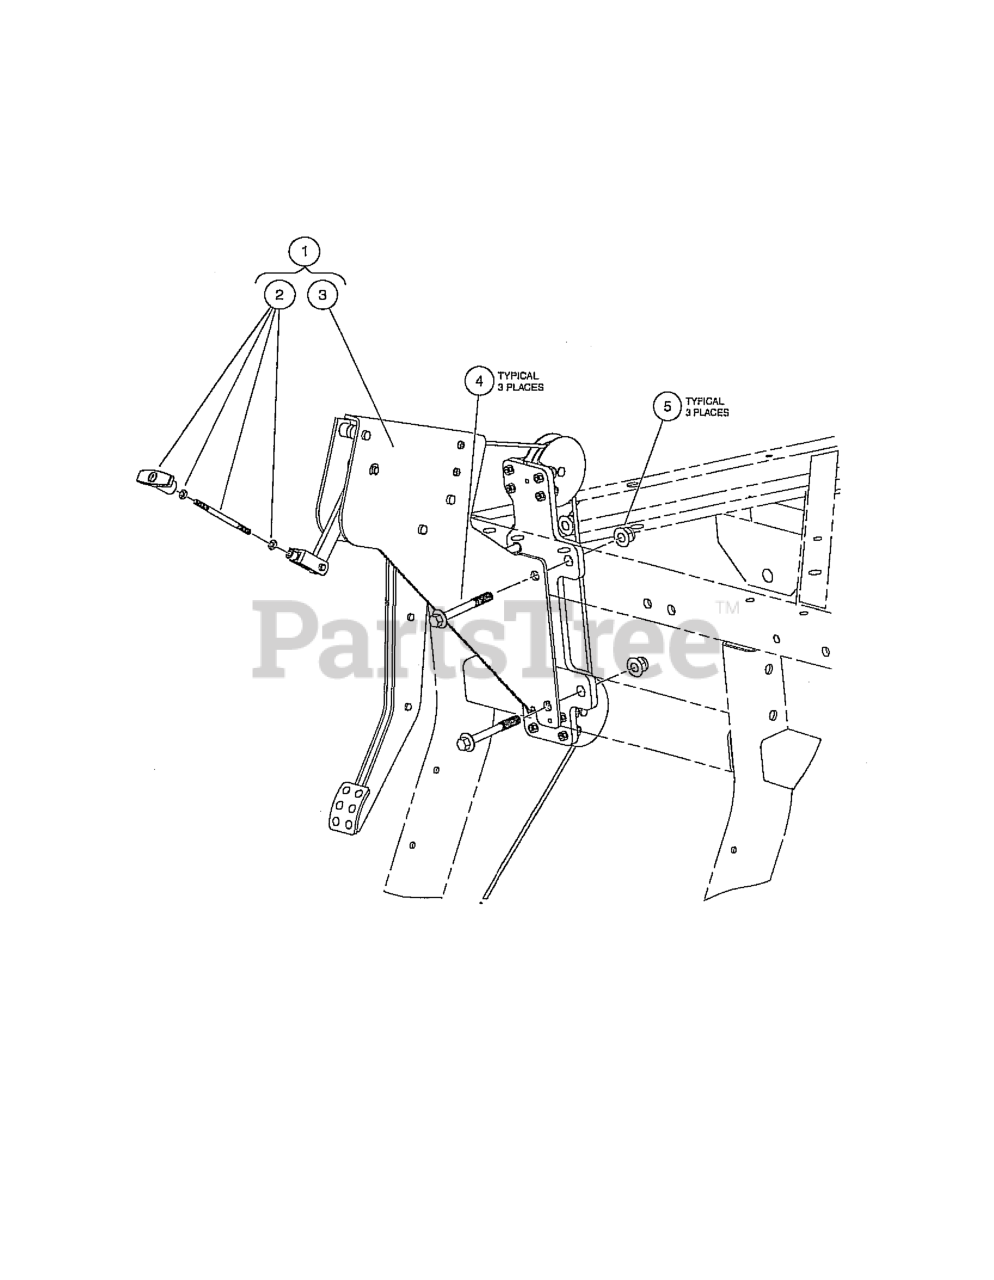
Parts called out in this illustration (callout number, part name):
1	PEDAL ASM, BRAKE, PARK
2	KIT-HANDLE-BRAKE-PARK
4	BOLT FLG, M8X1.25X65
5	LOCK NUT, FLG M8 X 1.25 NYLON
